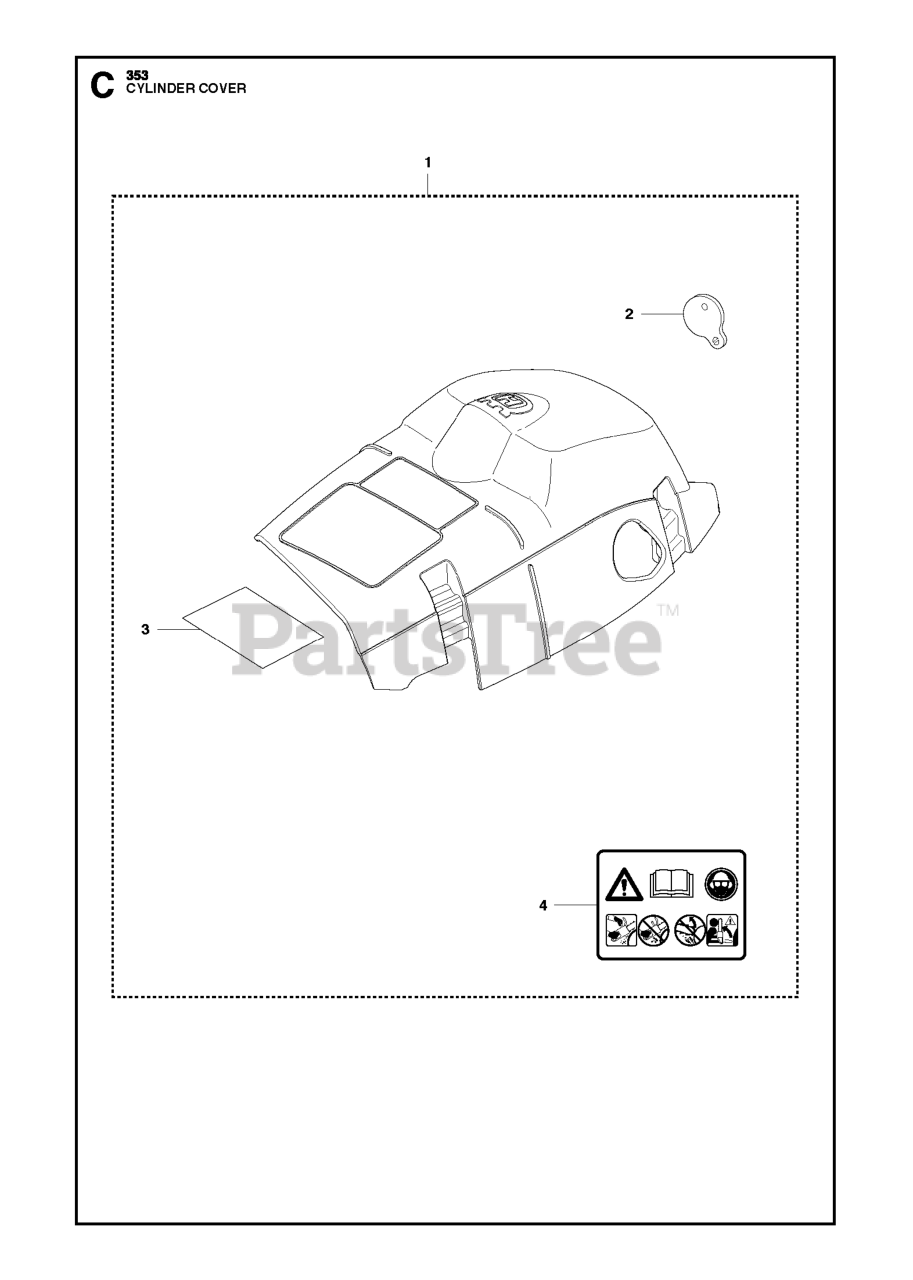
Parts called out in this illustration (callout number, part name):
1	CYLINDER COVER ASSY
1	CYLINDER COVER
2	COVER
3	INSULATING FOIL/CYLINDER COVER
